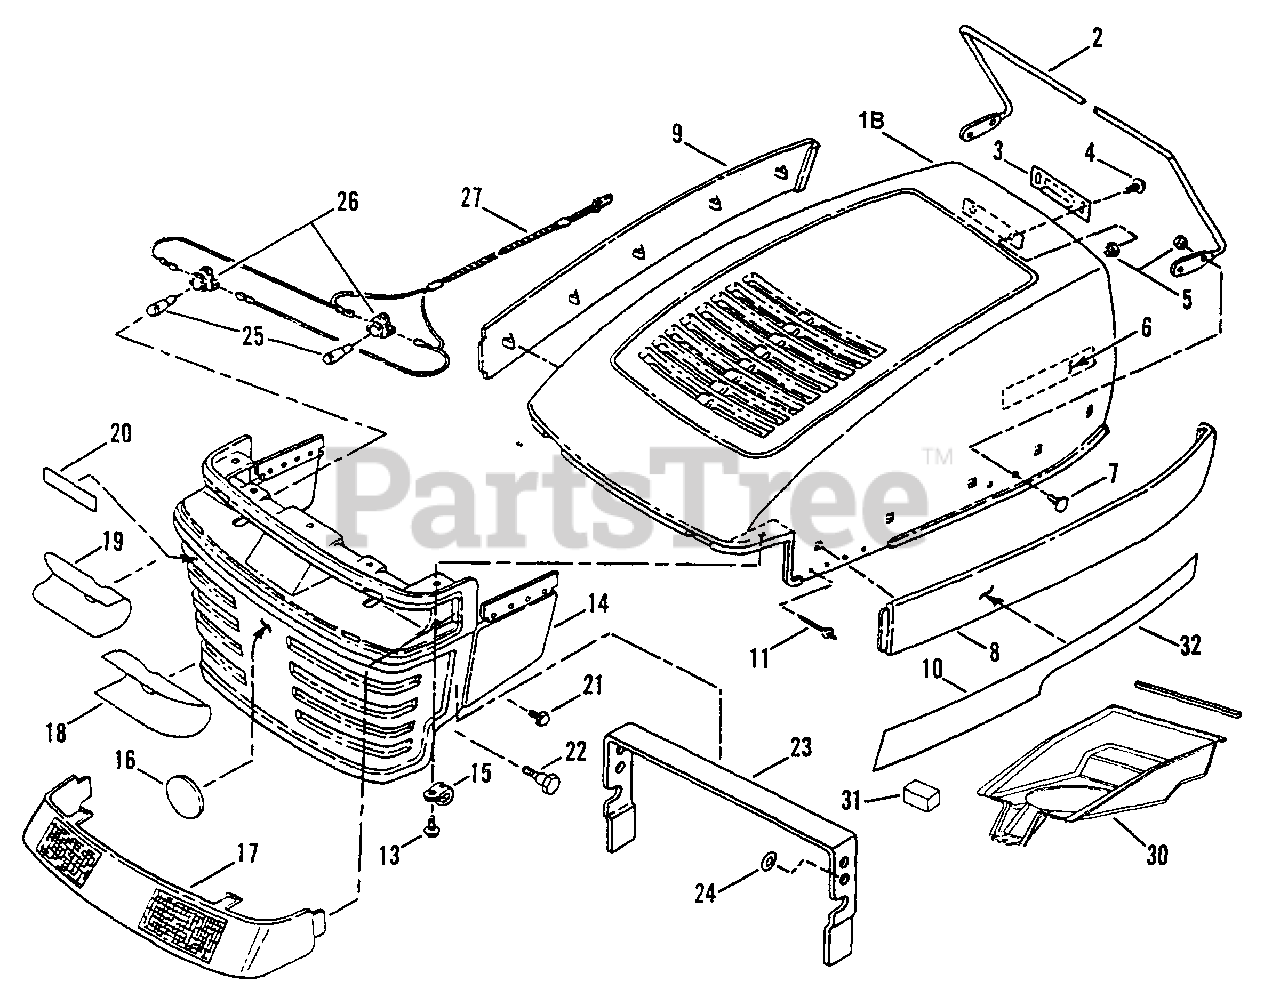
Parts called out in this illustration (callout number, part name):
1B	HOOD, Mozart
2	ROD, Hood Support
3	LATCH, Spring
4	SCREW, 1/4-20 x 5/8" Truss Head, Torx
5	NUT, 1/4-20 Hex Nyloc
6	DECAL - SNAPPER, 8" Molded Logo, Silver Letters
7	BOLT, 1/4-20 x 5/8" Flat Head Carriage
8	PANEL, Hood (Left Hand) (Black)
9	PANEL, Hood (Right Hand) (Black)
10	DECAL, Hood (Right Hand)
10	DECAL, Hood (Left Hand)
11	RIVET, 1/8 Pop
13	SCREW, M4.8 x 1.59 x 16.00 mm, Special
14	GRILLE, Hood
15	CLIP, "J"
16	DECAL, Molded Medallion
17	LENS, Grille (Headlights)
18	DECAL, Reflect (Left Hand)
19	DECAL, Reflect (Right Hand)
20	DECAL - SNAPPER, 4" Molded Logo
21	SCREW, 5/16-18 x 1/2" Self-Tapping
22	BOLT, Shoulder, 3/8-16 x 1 1/4" Hex Socket, Torx
23	BRACE, Hood Support
24	RETAINER, Bolt
25	BULB, Headlights
26	SOCKET, Headlight Bulb
27	HARNESS, Headlight Wiring
30	PLENUM,
31	FOAM, 2 x 2 x 3.5
32	FOAM, 1/2 x 3/4 x 14.25
